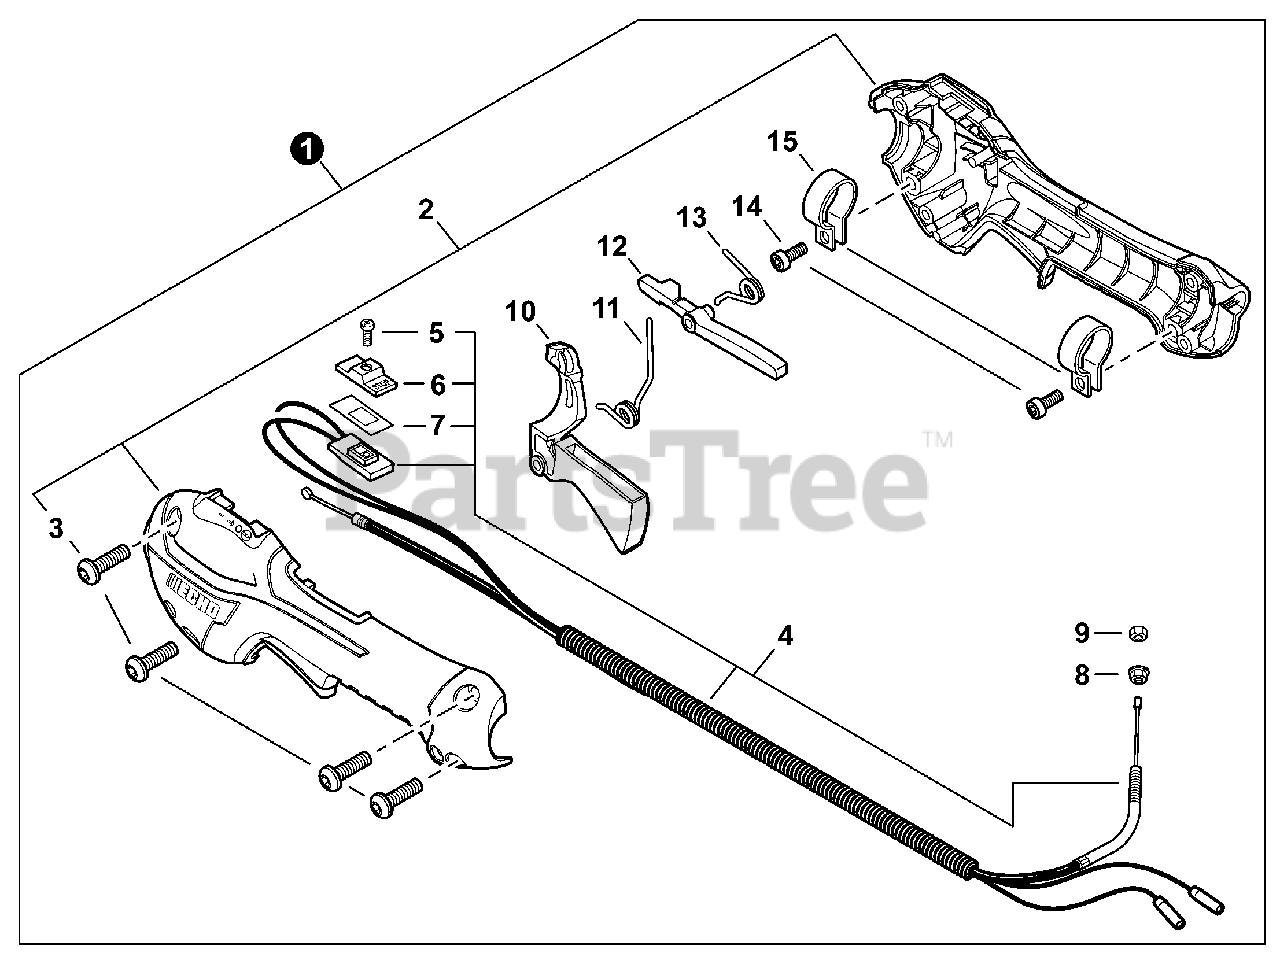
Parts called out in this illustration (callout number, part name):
1	CONTROL HANDLE ASSY
2	CONTROL HANDLE KIT
3	BOLT, TORX 5×16
4	CABLE ASSY, CONTROL
5	SCREW 3×10
6	KNOB, SWITCH - ORANGE
7	SEAL, SWITCH
8	NUT, FLANGE M6
10	TRIGGER, THROTTLE
11	SPRING, TORSION
12	LEVER, THROTTLE LOCKOUT
13	SPRING, TORSION
14	BOLT, TORX 5×16
